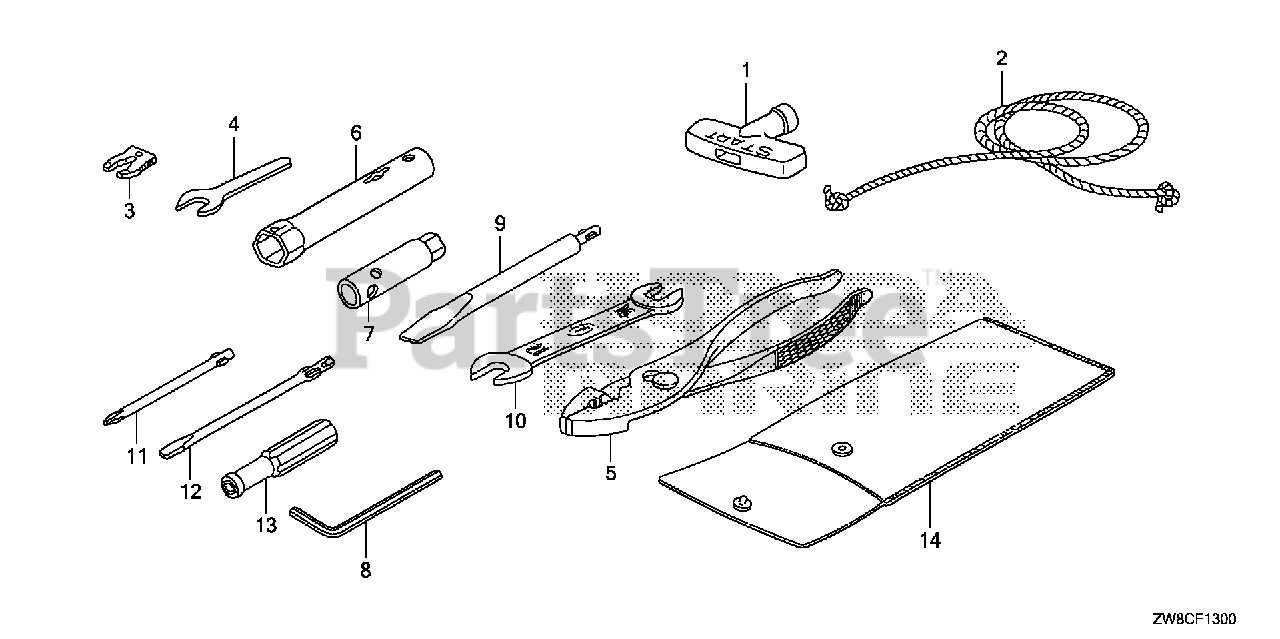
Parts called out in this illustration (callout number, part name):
1	GRIP, STARTER
2	ROPE, RECOIL STARTER (1300MM)
3	CLIP, EMERGENCY LOCK
5	PLIERS (135) (RIKEN)
6	WRENCH, SPARK PLUG
7	WRENCH, BOX (10MM) (NOT AVAILABLE)
8	WRENCH, HEX. (4MM)
9	SCREWDRIVER, CHECK BOLT
10	WRENCH (10X12) (OPEN END)
11	SCREWDRIVER 1, PHILLIPS (NO.2)
12	SCREWDRIVER 3, STRAIGHT SLOT (NO. 2)
13	GRIP, SCREW DRIVER
14	BAG, TOOL (160MM)
